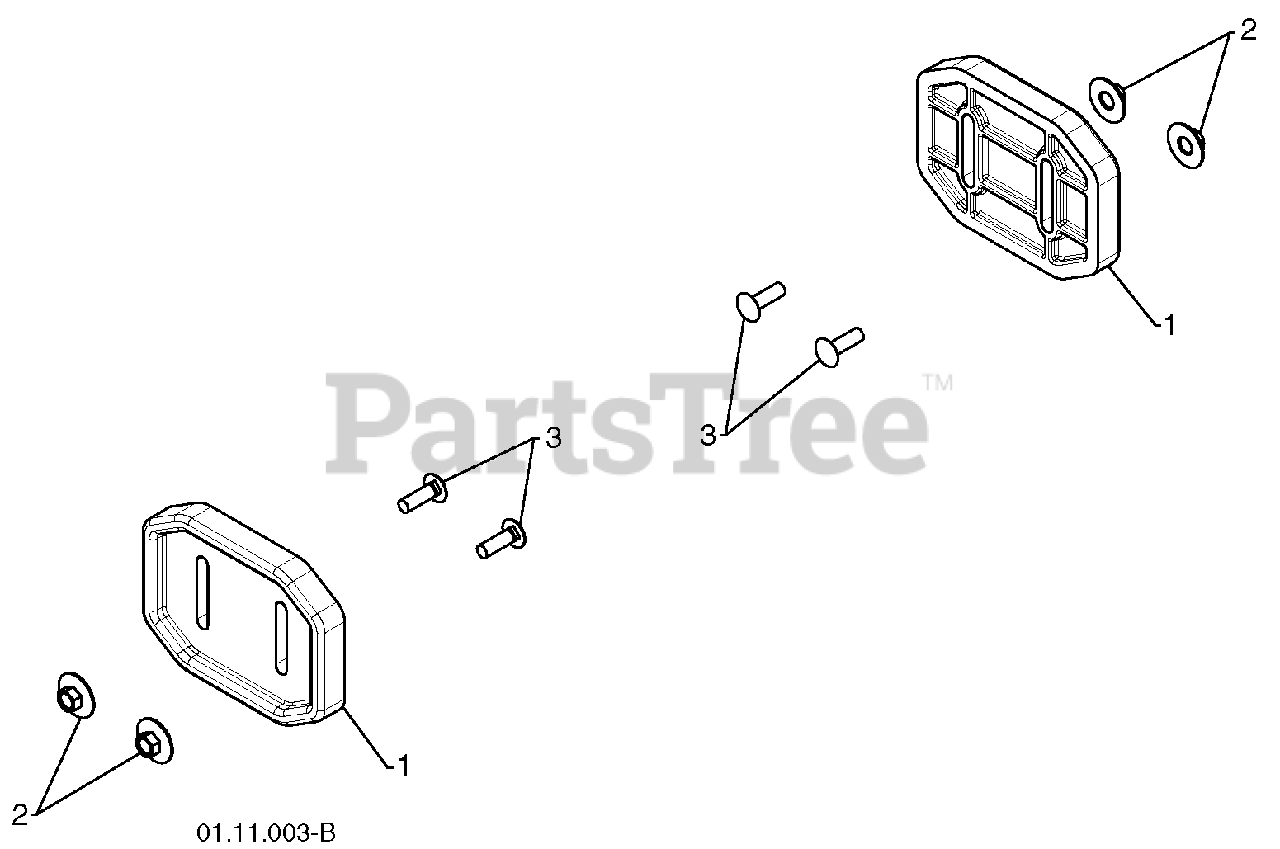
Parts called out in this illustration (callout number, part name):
1	SKID.PLATE.PLASTIC.
2	BOLT.CARRIAGE.5/16-18
3	NUT.FLANGE.HEX.5/16X18.BLACK
